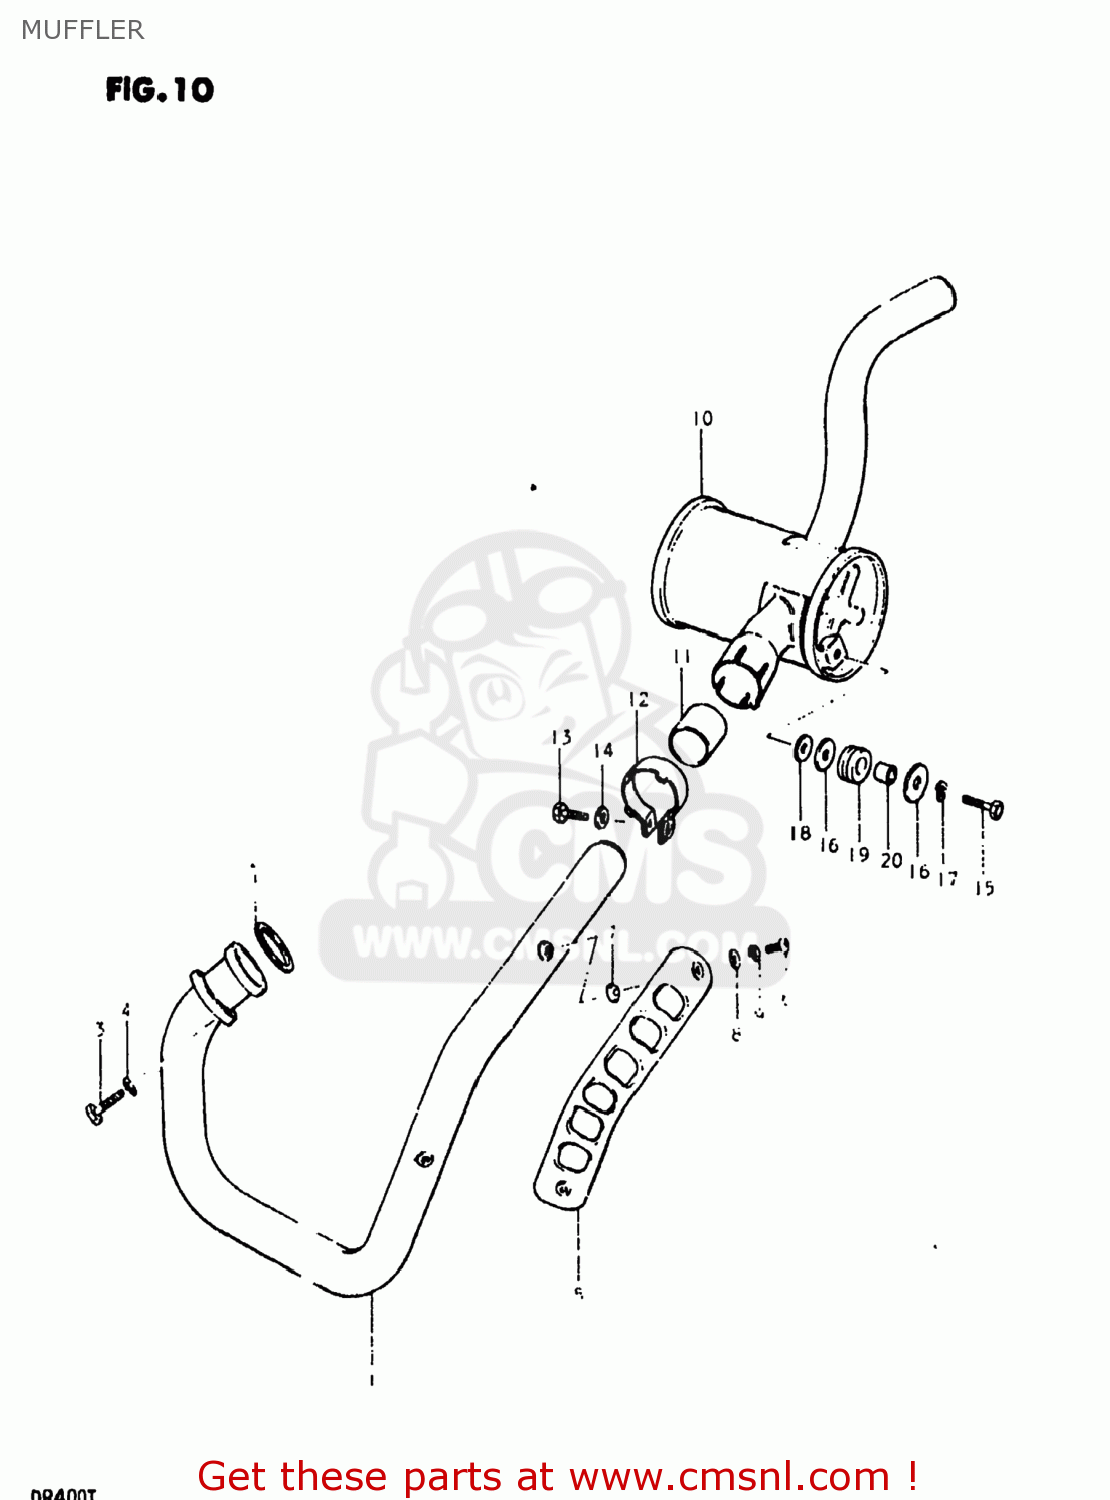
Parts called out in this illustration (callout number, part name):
1	PIPE,EXHAUST
2	GASKET,EXHAUST PIPE (NAS)
3	BOLT (8X30)
4	LOCK WASHER
5	COVER,EXHAUST PIPE
6	SCREW
7	GASKET 6.2X12X1.5 (MCA)
8	WASHER
9	LOCK WASHER
10	BODY,MUFFLER
11	CONNECTOR,MUFFLER
12	CLAMP,MUFFLER CONNECTOR
13	BOLT(8X14)
14	WASHER
15	BOLT (8X30)
16	WASHER (8.5X29X1.6)
17	LOCK WASHER
18	GASKET
19	CUSHION
20	SPACER (8.6X13.8X13)
